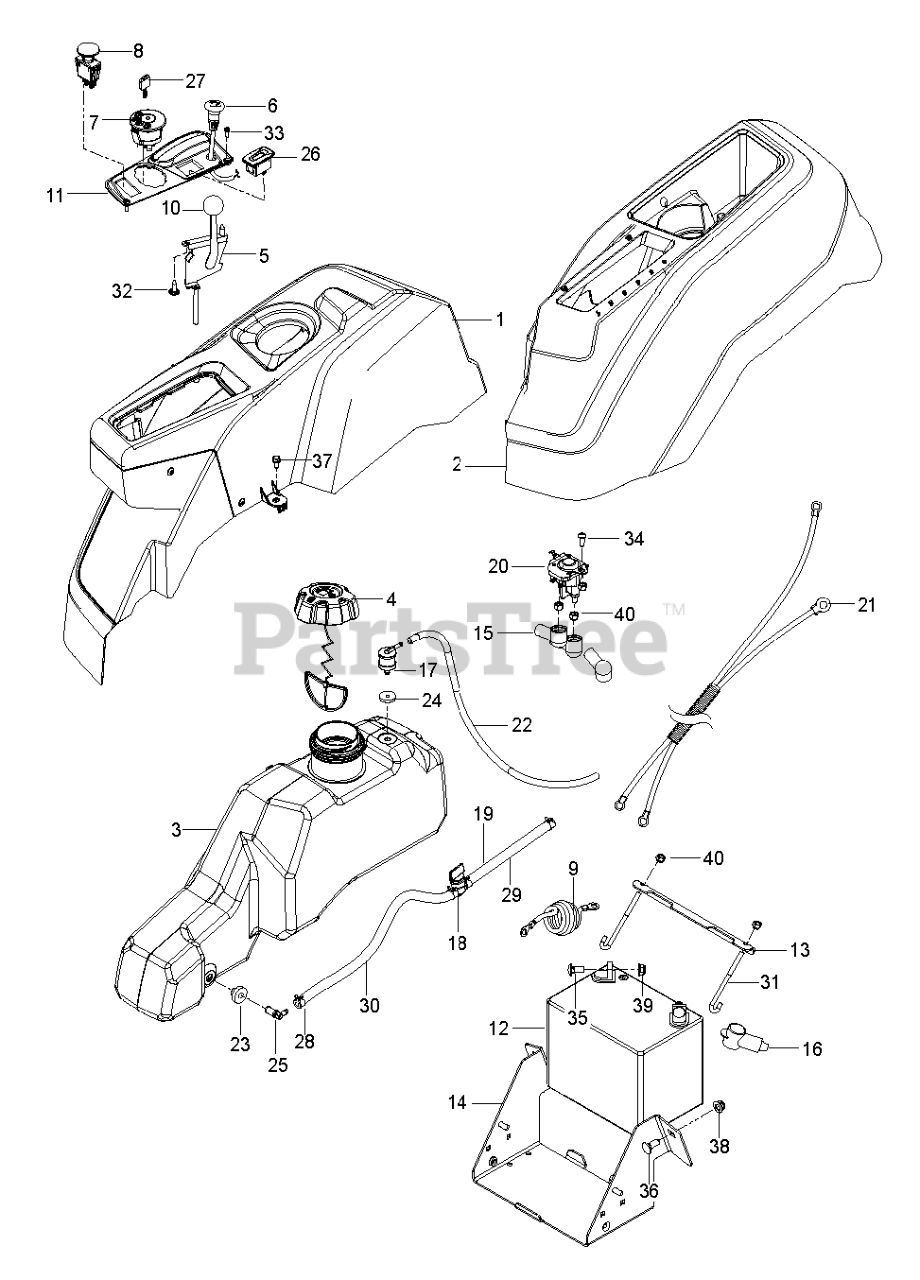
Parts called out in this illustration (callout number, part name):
1	CONSOLE.ASSY.RZ.REFRESH.RH
2	CONSOLE.LH.ASM
3	TANK.ASM3"NECK.NOCAP.NOSHDRZ18
4	CAP ASSY FUEL 3" GRAY
5	THROTTLE CABLE W/KNOB
6	CHOKE.PUSH-IN.STYLE
7	RP IGNITION SWITCH
8	RP SWITCH.PTO.TERMINAL.STD.RED
9	CABLE BATTERY POS RZ
10	FUEL.HOSE.SHUT.OFF.ASM.10".3"
11	CONTROL.PANEL.RZ.REFRESH.RH
12	BATTERY, 12 V 330 AMP
13	BRACKET.PNT.MOUNT.BATTERY.EDIP
14	BOX.PNT.BATTERY.RZ.EDIP
15	TERMINAL COVER
17	VALVE.FUEL.CHECK
18	FUEL VALVE
19	FUEL.HOSE.SHUT.OFF.ASM.10".18"
21	HARNESS.BTTRY.CABLE.RZ.REFRESH
22	HOSE.3/16".VAPOR.LINE.50"LGTH
23	GROMMET.ROV.SENTEC
24	GROMMET.ROV.SENTEC
25	GUAGE.SRVCMNDR.HRMTR.
26	CANNISTER, CARBON
27	KEY.CHAIN.BLISTER.PACK.GEN.USA
28	HOSE CLAMP
29	HOSE.1/4".LOW.PERM.FUEL.LN.10"
30	HOSE 1/4" LOW PERMEATION FUEL
31	HOOK.J.BATTERY
32	SCREW.PAN.HEAD.#10
33	SCREW 6-19X.437
35	GSPW Bolts
39	NUT HEXAGON FLANGE 5/16-18 ST
40	5/16-18 NYLOC FLANGE NUT
